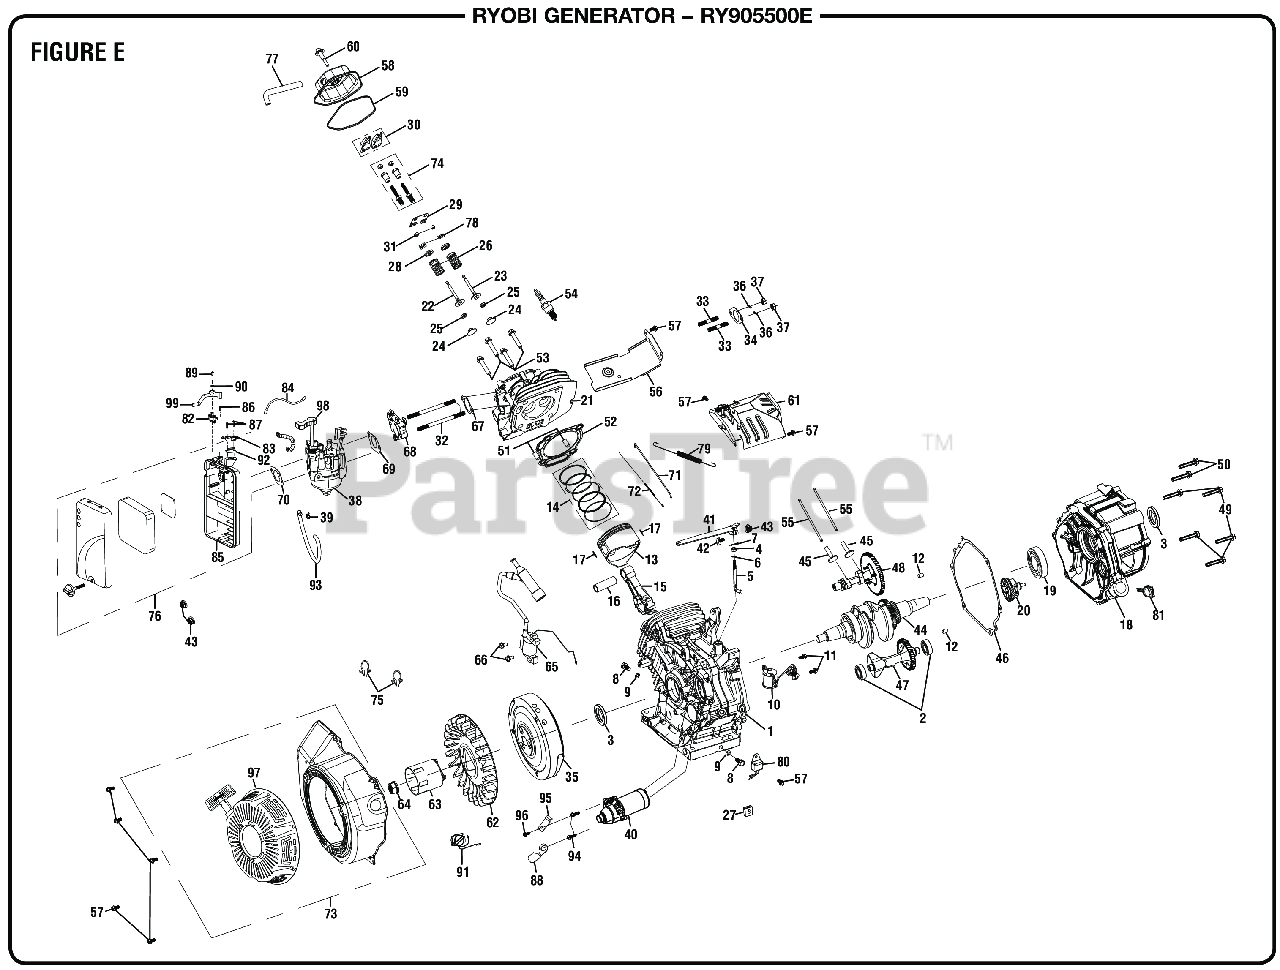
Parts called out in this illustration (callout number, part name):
1	Crankcase
2	Ball Bearing
3	Oil Seal
4	Governor Arm Shaft Seal
5	Governor Arm Shaft
6	Governor Arm Shaft Washer
7	Lock Pin
8	Drain Plug Bolt.
9	Drain Plug Washer
10	Oil Level Switch Assembly
11	Bolt (M6 x 16 mm)
12	Casecover Dowel Pin
14	Piston Scraper Ring Set
15	Connecting Rod Assembly
16	Piston Pin
17	Piston Clip
18	Crankcase Cover Assembly
19	Ball Bearing
20	Governor Assembly
21	Cylinder Head
22	Intake Valve
23	Exhaust Valve
24	Intake Valve Returner
25	Oil Seal Valve
26	Valve Spring
27	Starter Assembly Rubber
28	Exhaust Valve Spring Seat
29	Push Rod Guide Plate
30	Rocker Assembly
32	Stud Bolt
33	Stud Bolt
34	Exhaust Packing
35	Flywheel Assembly
36	Spring Washer
37	Hex Nut (M8)
38	Carburetor Assembly
39	Fuel Line Clip
40	Starting Motor Assembly
41	Governor Arm
42	Governor Arm Bolt
43	Hex Nut (M6)
44	Crankshaft Assembly
45	Valve Lifter
46	Casecover Package
47	Balancing Shaft
48	Camshaft Assembly
49	Bolt (M8 x 35 mm)
50	Bolt (M8 x 40 mm)
51	Dowel Pin
52	Cylinder Head Gasket
53	Bolt (M10 x 80 mm)
54	Spark Pulg
55	Push Rod.
57	Bolt (M6 x 12 mm)
58	Cylinder Head Cover Comp
59	Headcover Packing
60	Lock Bolt
61	Upper Shroud Assembly
62	Recoil Starter Fan
63	Starter Pulley
64	Hex Nut (M5)
65	Ignition Coil Assembly
66	Bolt (M6 x 25 mm)
67	Intake Packing
68	Carburetor Insulator
69	Carburetor Packing
70	Carburetor Spacer
71	Governor Rod
72	Throttle Return Spring
73	Recoil Starter Assembly
74	Rocker Arm Adujuster
76	Air Cleaner Assembly
77	Breather Tube
78	Locking Flaps
79	Governor Spring
80	Amplifier
81	Dipstick
82	Fuel Valve
83	Enginge Stop Switch
84	Flameout Wire
85	Air Cleaner Bottom Cover
86	Screw (M6 x 10 mm, Pan Hd.)
87	Screw (St 2.9 x 16 mm, Pan Hd)
88	Clamper Cord A
89	Screw (M4 x 10 mm, Phillips Pan Hd.)
90	Washer (ID4.3 x OD10 x 0.9t)
91	Switch Assembly
92	Engine Switch Bracket
93	Fuel Hose (300 mm)
94	Bolt (M6 x 28 mm)
95	Clamper Cord A
96	Bolt (M6 x 8 mm)
97	Recoil cover
98	Choke Lever (Grey)
99	Control Lever (Grey)
